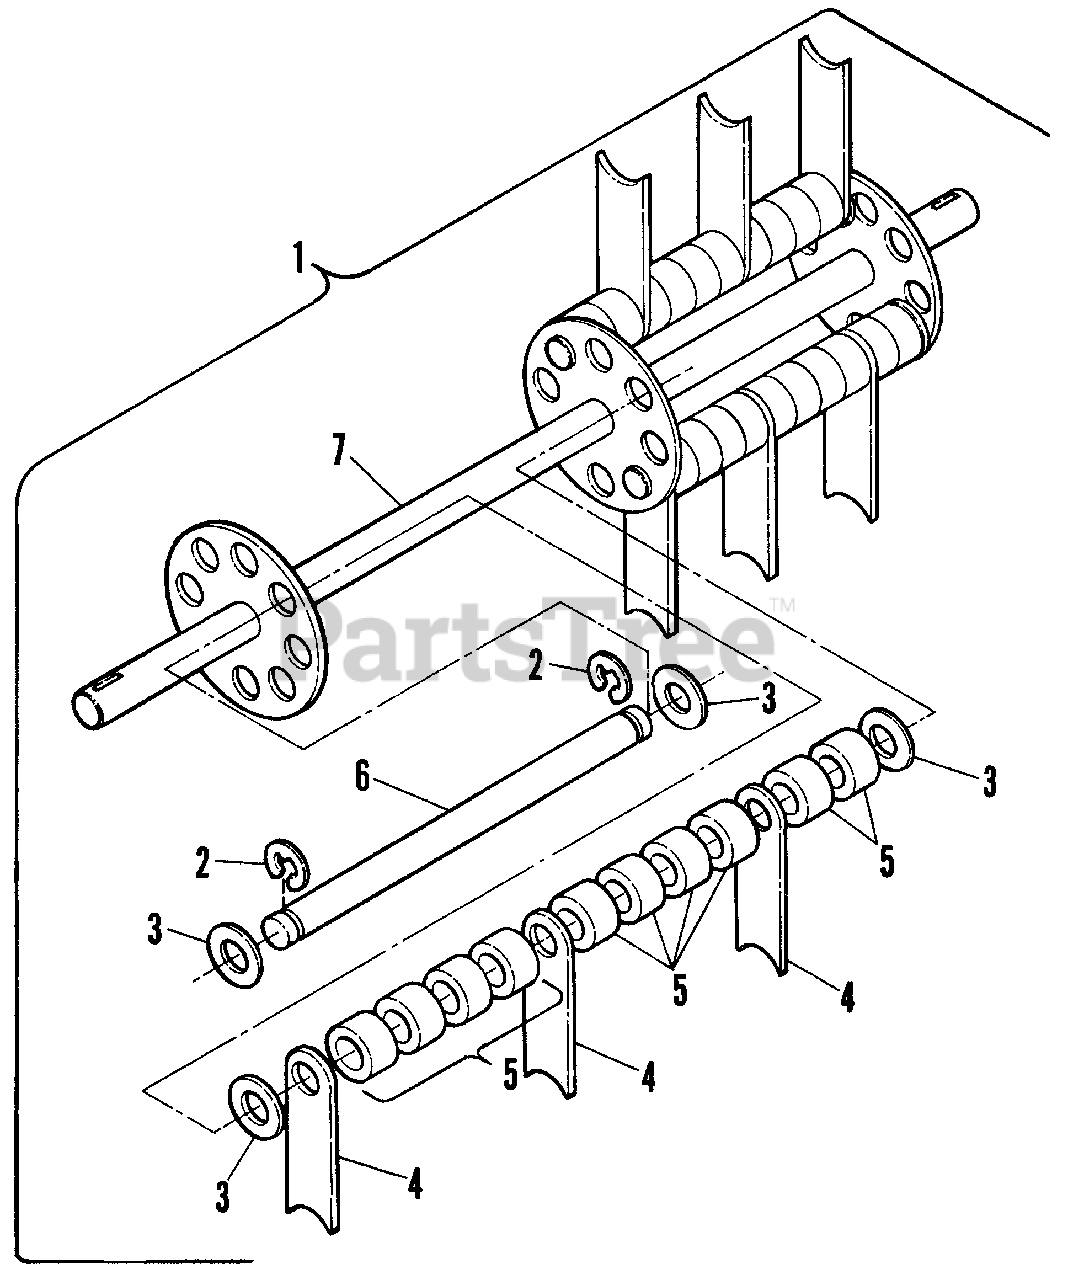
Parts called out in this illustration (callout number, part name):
1	RAKING SHAFT, COMPLETE
2	SNAP RING
3	MAIN SHAFT WASHER
6	SATELLITE SHAFT
7	MAIN SHAFT
